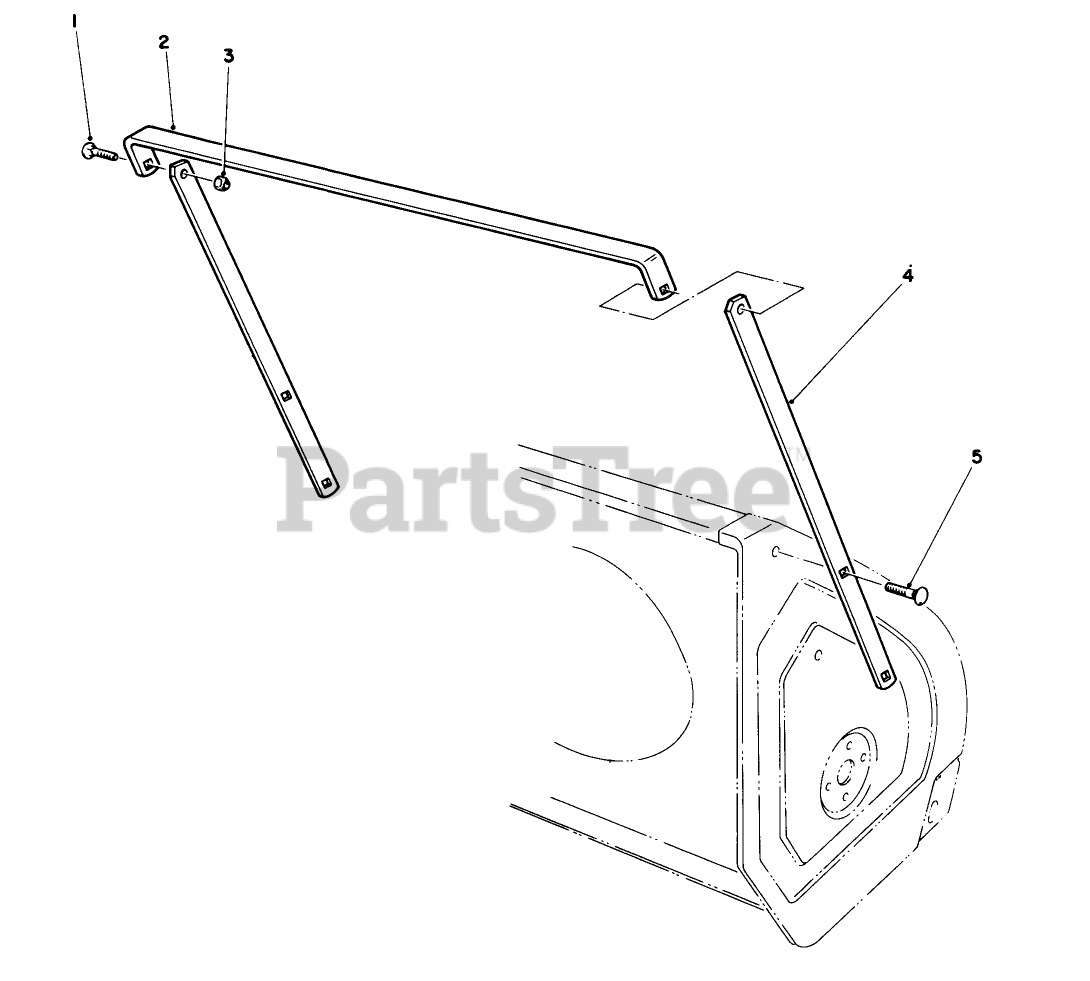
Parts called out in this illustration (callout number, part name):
1	SCREW-CARR
3	NUT-LOCK, NI
4	Breaker-Side
5	BOLT-CARR
